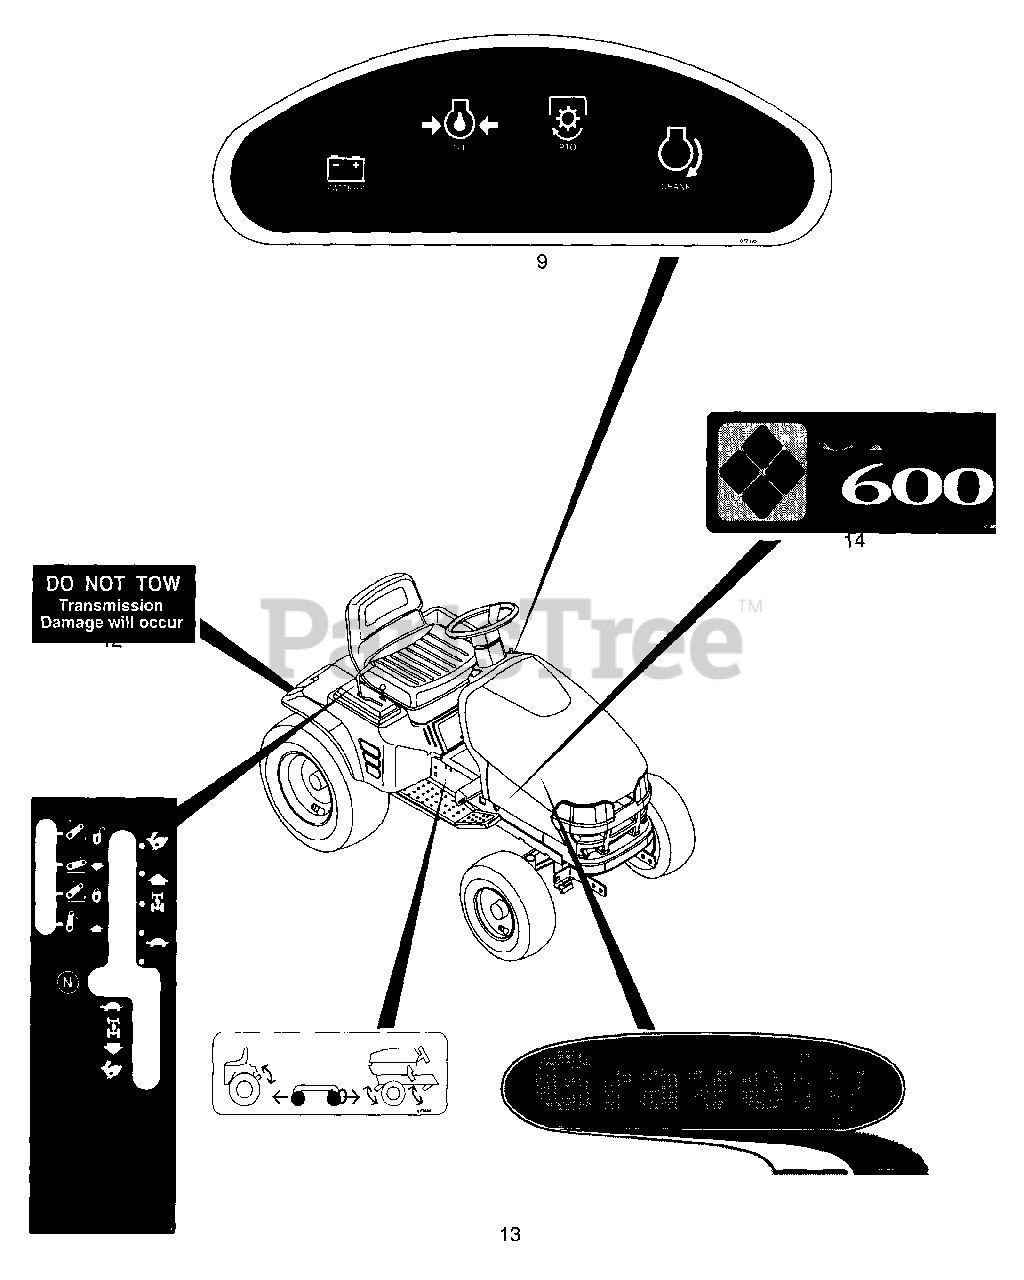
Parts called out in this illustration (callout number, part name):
9	Decal-Dash w/Lights
10	Decal-Lift Selector
11	Decal-Control Console
12	Tranmission Decal
13	Decal-GT 600
14	Decal Set-Hood GT 600
